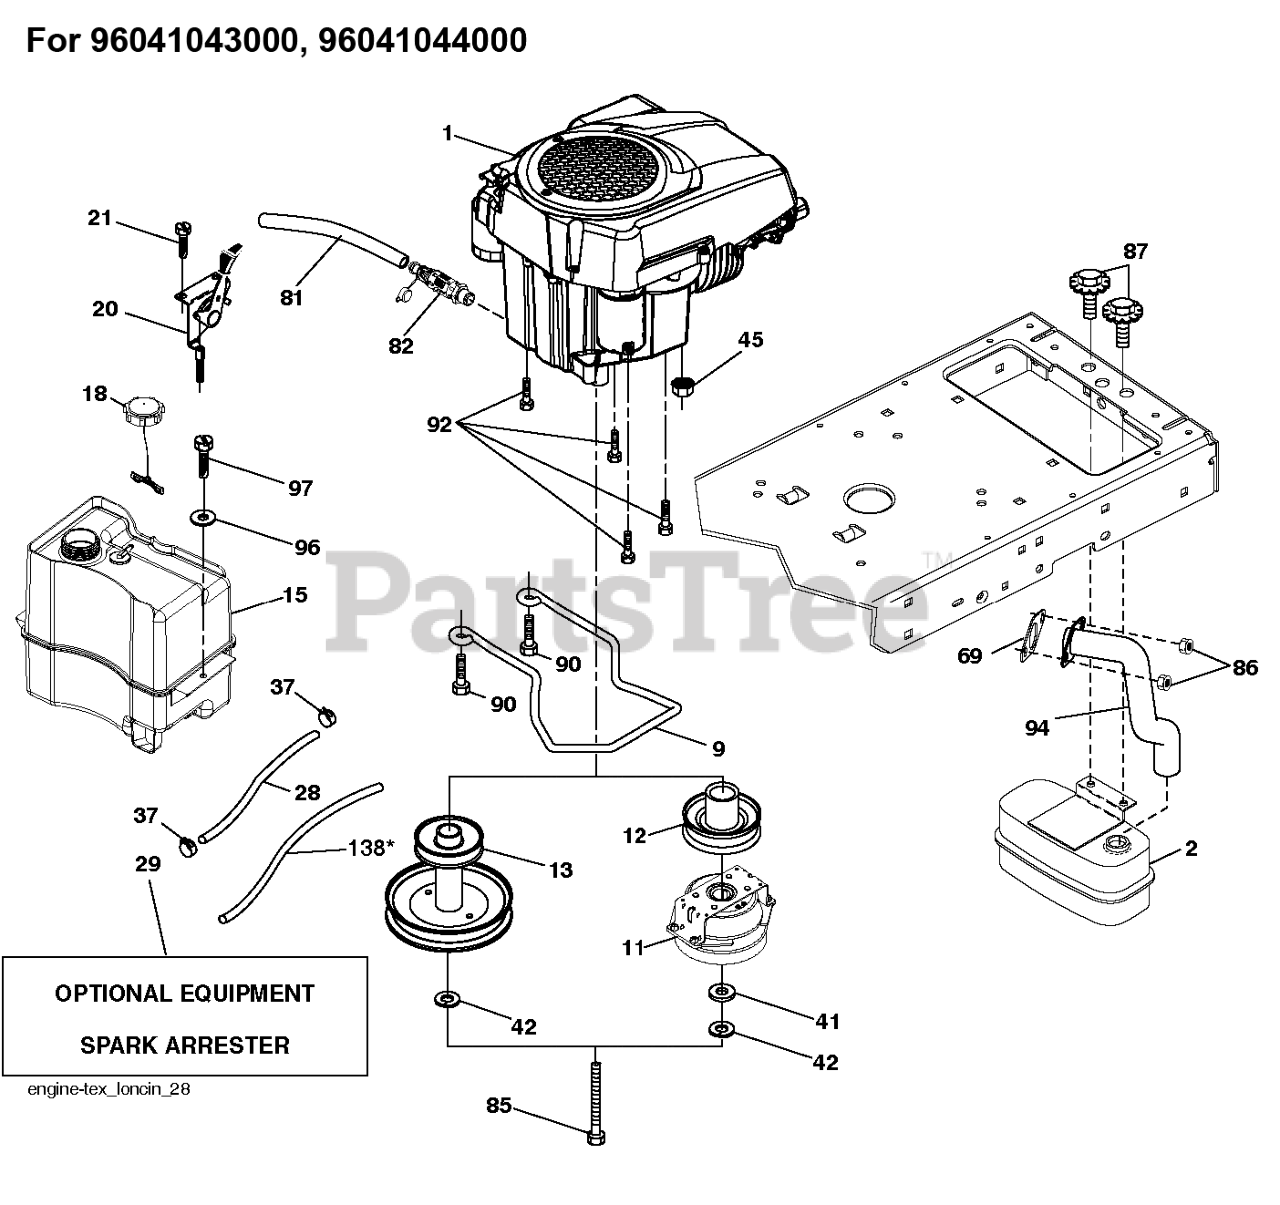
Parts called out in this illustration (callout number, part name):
1	ENGINE.LONCIN.SPARE./608
1	ENGINES
2	MUFFLER.ASM.SINGLE
9	KEEPER.BELT.ENG.4.25"2.BLT.431
9	Keepers
11	CLUTCH.OGURA.4.4PD.GT1.5-EH13V
12	PULLEY.ENGINE.TUFFTORQ
13	ENGINE.PULLEY
15	Tanks
15	FUEL.TANK.ASM.NON-EPA
18	CAP ASM.FUEL.2.25"FR.
18	FUEL CAP
20	CONTROL.TH/CK.C.
28	LINE.FUEL.20
29	KIT.SPARK ARRESTOR 794945 B&S
37	HOSE CLAMP
41	WASHER
45	NUT HEXAGON WITH FLANGE, SERRA
69	GASKET GASKET.EXHAUST. LONCIN
81	TUBE, DRAIN OIL ASM.
82	VALUE.OIL.DRAIN
85	CLUTCH BOLT7/16-20X3.5 GR524HR
85	BOLT.HEX.7/16-20X4.GR5.1.5BLUE
86	NUT.HEX.FLANGE.TOPLOCK
87	BOLT.5/16-18UNCX3/4 W/SEMS.BLK
90	SCREW 3/8-16X1
92	SCREW 3/8-16X1
94	TUBE TUBE.EXHAUST.LONCIN 608.T
97	SCREW HEXWSHR 1/4-20X3/4
